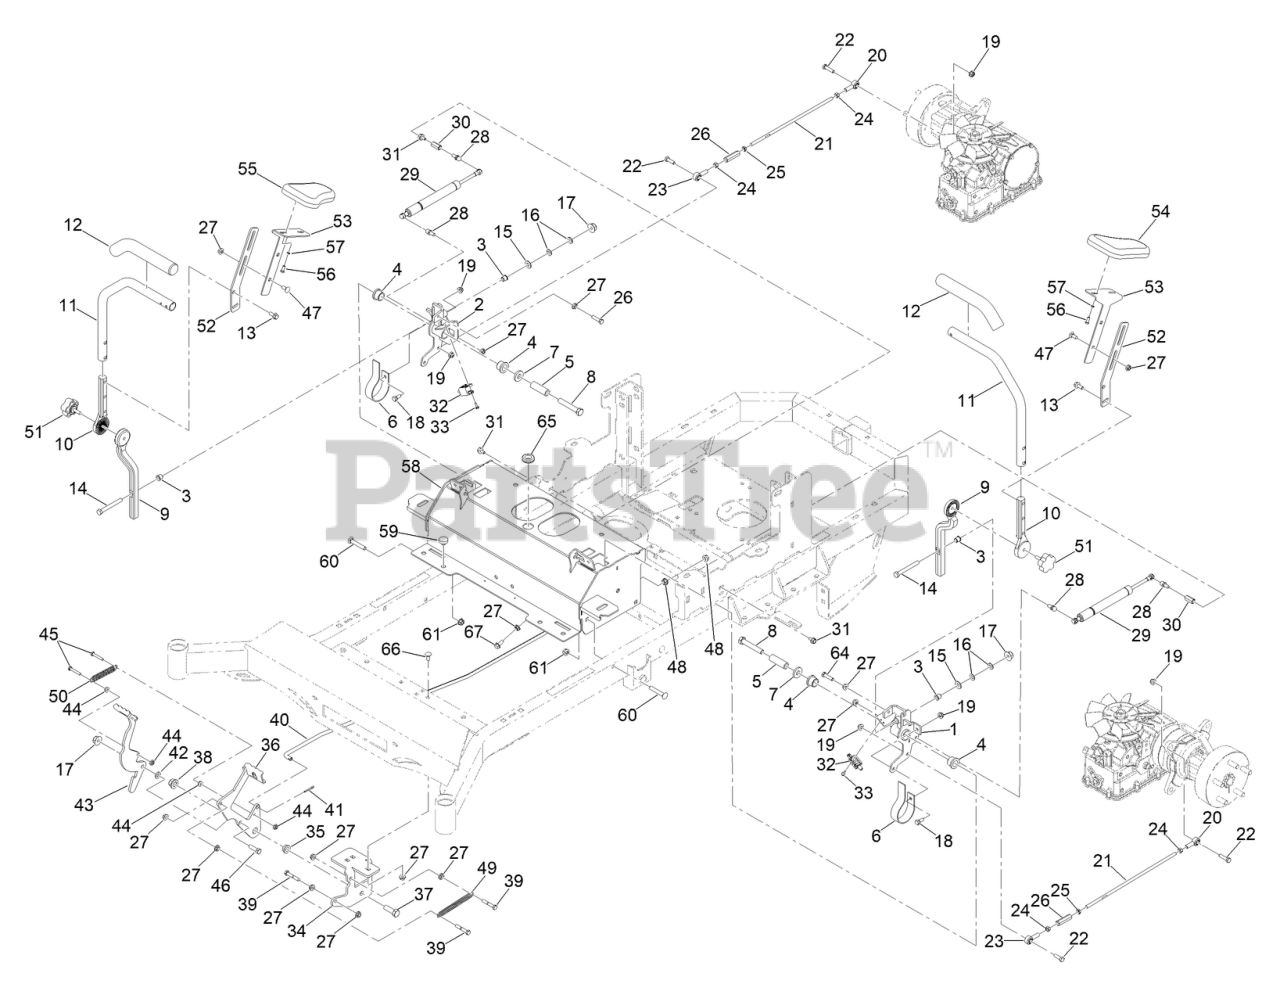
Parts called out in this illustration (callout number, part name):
1	LH PIVOT ASM
2	RH PIVOT ASM
3	BUSHING-FLANGE
4	BUSHING-FLANGE
5	SLEEVE-PIVOT
6	SPRING-LEAF
7	1/2 FENDER WASHER 1-1/4IN OD ZINC
8	1/2-13 X 3 HEX C/S GR 5 ZINC W/LOCTITE
9	ADJUSTABLE LWR DRIVE ARM
10	ADJUSTABLE UPP DRIVE ARM
11	MOWER DRIVE HANDLE TUBE ABC
12	CONTROL ARM HANDLE GRIP
13	SCREW-HHF
14	SCREW-HH
15	WASHER-FLAT
16	WASHER-BELLEVILLE
17	3/8-16 NYLON INSERT FLANGE L/NUT YZ
18	SCREW-HH
19	NUT-HF, NI
20	5/16-24 SPHER ROD END ZINC RH THD FEM
21	TRANS DRIVE ARM LINKAGE STANDARD TRANS
22	SCREW-HH
23	ROD END-BALL JOINT
25	NUT-JAM
26	NUT-SLEEVE
28	5/16-18X1.286 DAMPER BALL STUD (.562 TL)
29	CONTROL ARM DAMPER
30	STANDOFF-HEX
31	SCREW-HHF
32	NO PLUNGER LIMIT SWITCH
33	8-32 X 1/2 IND. HWH SLOT TYPE F TCS ZINC
34	MWR FRAME BRAKE MTG BRKT BLACK
35	1/2IN ID X 3/4IN OD X 3/8IN FLANGE BUSH
36	MWR BRAKE LOCK LEVER ASSY BLACK
37	SCREW-HH
38	NUT-LOCK
40	MWR BRAKE LINKAGE
41	PIN-COTTER
42	3/8 ID X 3/4 OD X .125 THK BRONZE WASHER
43	MWR BRAKE UNLOCK LEVER ASSY BLACK
44	1/4-20 HEX FLANGE NUT
45	1/4-20 X 1-1/4 HEX C/S GR 2 ZINC
46	SCREW-HH
47	BOLT-CARR
48	3/8-16 HEX FLANGE NUT W/SERR ZINC YELLOW
49	2020 MWR BRAKE PEDAL TENSION SPRING
50	MWR BRAKE PEDAL RELEASE SPRING
51	5/16-18 X 1 SL 5-LOBE MALE ST KNOB 1.90
52	MWR ARM PAD TUBE MTG BRKT BLACK
53	MWR ARM PAD MTG BRKT BLACK
54	2020 MWR DRIVE ARM SUPPORT PAD LT
55	2020 MWR DRIVE ARM SUPPORT PAD RT
56	SCREW-HSBH
57	1/4 EXT TOOTH LOCKWASHER ZINC
58	GT-TRAC ASM
59	PUSH-IN RUBBER BUMPER MWR FLOOR
60	SCREW-CARR
64	SCREW-HH
65	GROMMET-RUBBER
66	BOLT-CARR
67	5/16-18 X 3/4 HEX FLANGE BOLT GR 8 YZ
